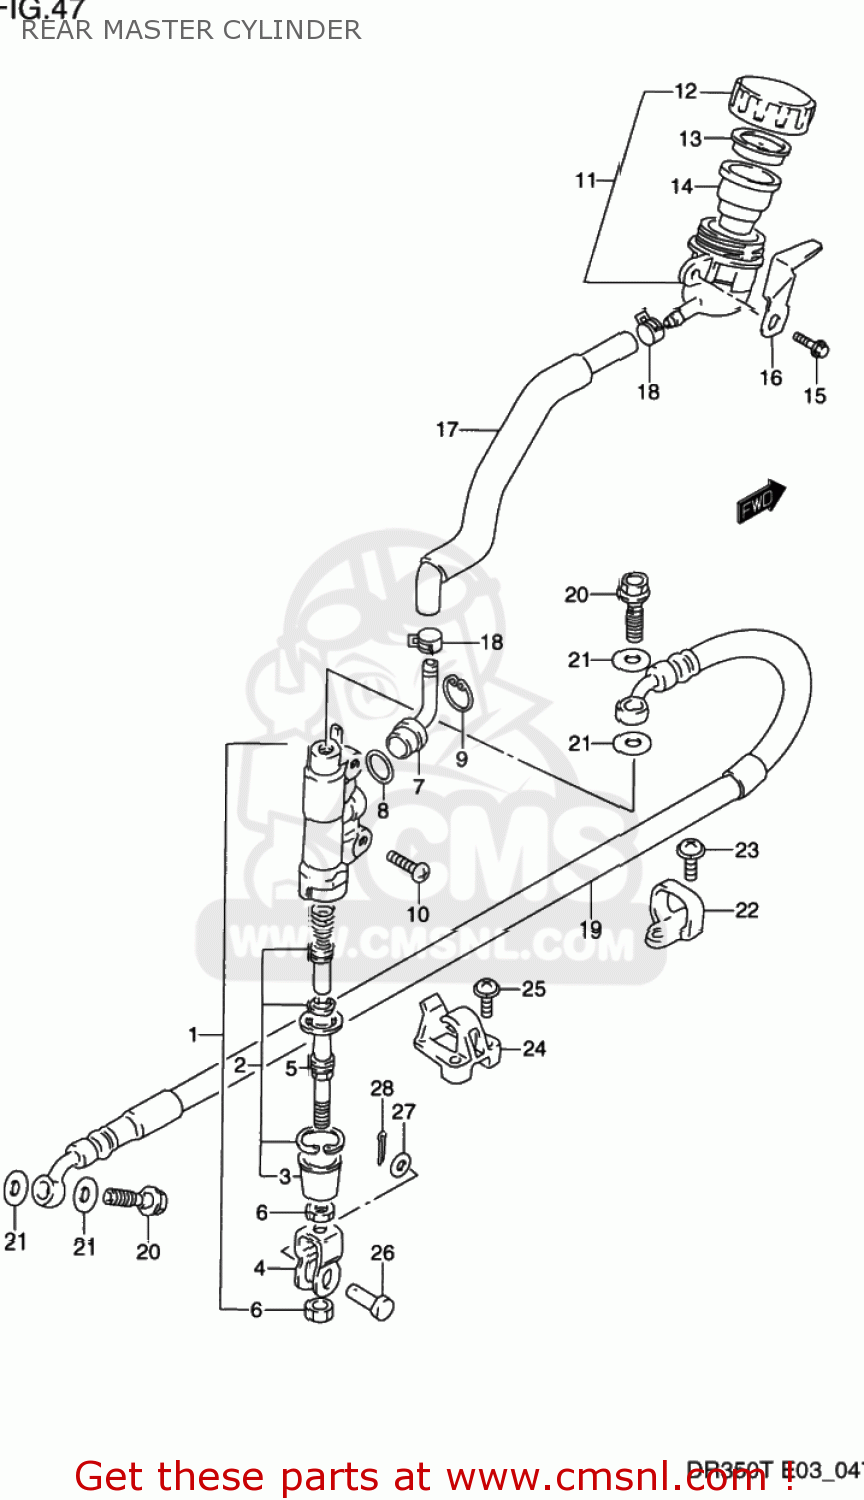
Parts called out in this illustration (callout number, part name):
1	CYLINDER ASSEMBLY,REAR MASTER
2	PISTON/CUP SET
3	BOOT
4	YOKE
5	ROD,PUSH
6	NUT
7	CONNECTOR
8	O RING
9	CIRCLIP
10	SCREW
11	TANK ASSY,RR BRAKE RESERVOIR
12	CAP
13	PLATE
14	DIAPHRAGM
15	BOLT
16	GUARD,RSVR TANK CAP
17	HOSE COMP,RESERVOIR TANK
18	CLIP
19	HOSE,RR BRAKE
20	BOLT UNION
21	WASHER(10X15X1.5)
22	GUIDE,RR BRAKE HOSE
23	SCREW
24	GUIDE,RR BRAKE HOSE
25	SCREW
26	PIN(8X20)
27	WASHER(8.5X13X1.6)
28	PIN 20X15
